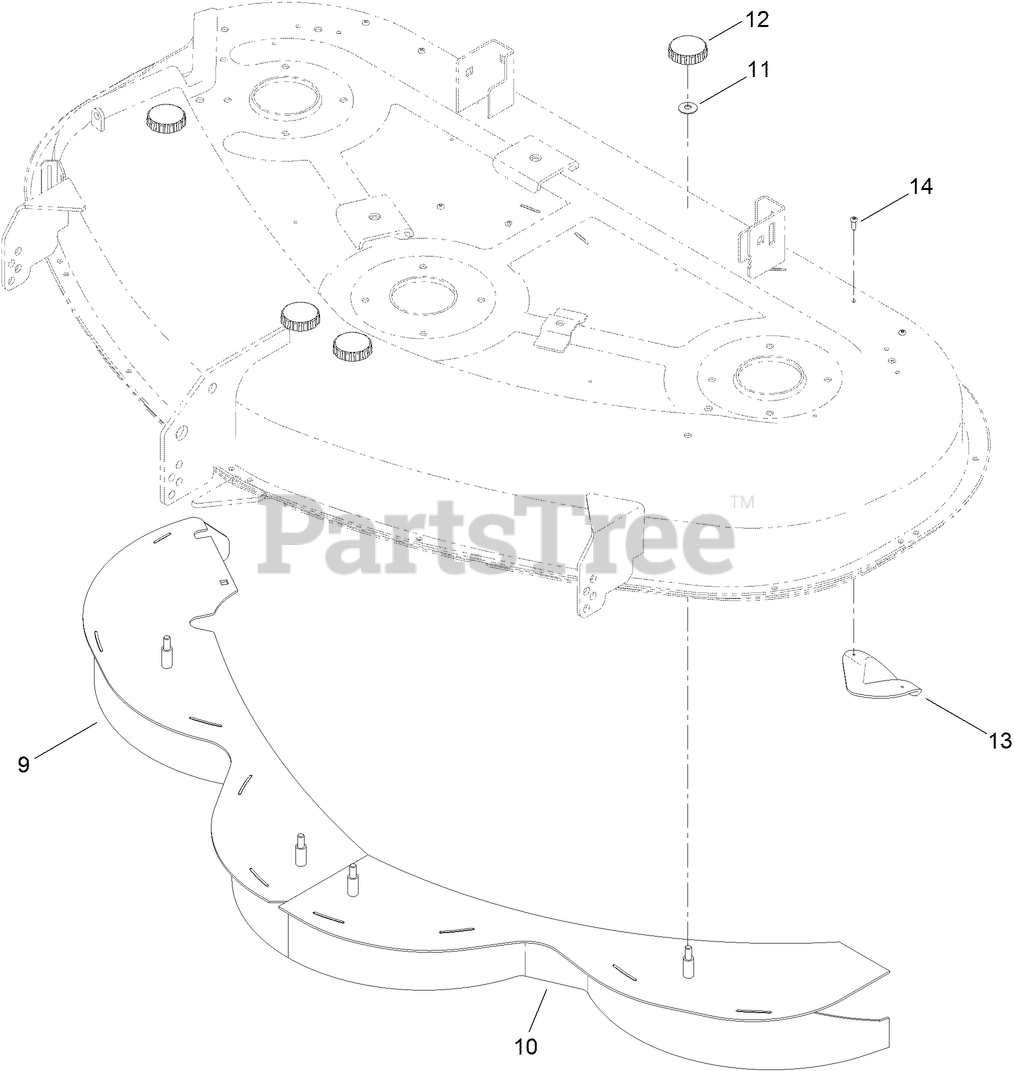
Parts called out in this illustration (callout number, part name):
9	RH BAFFLE ASM
10	LH BAFFLE ASM
11	WASHER-BELLEVILLE
13	PLATE-KICKER
14	SCREW-PPH
